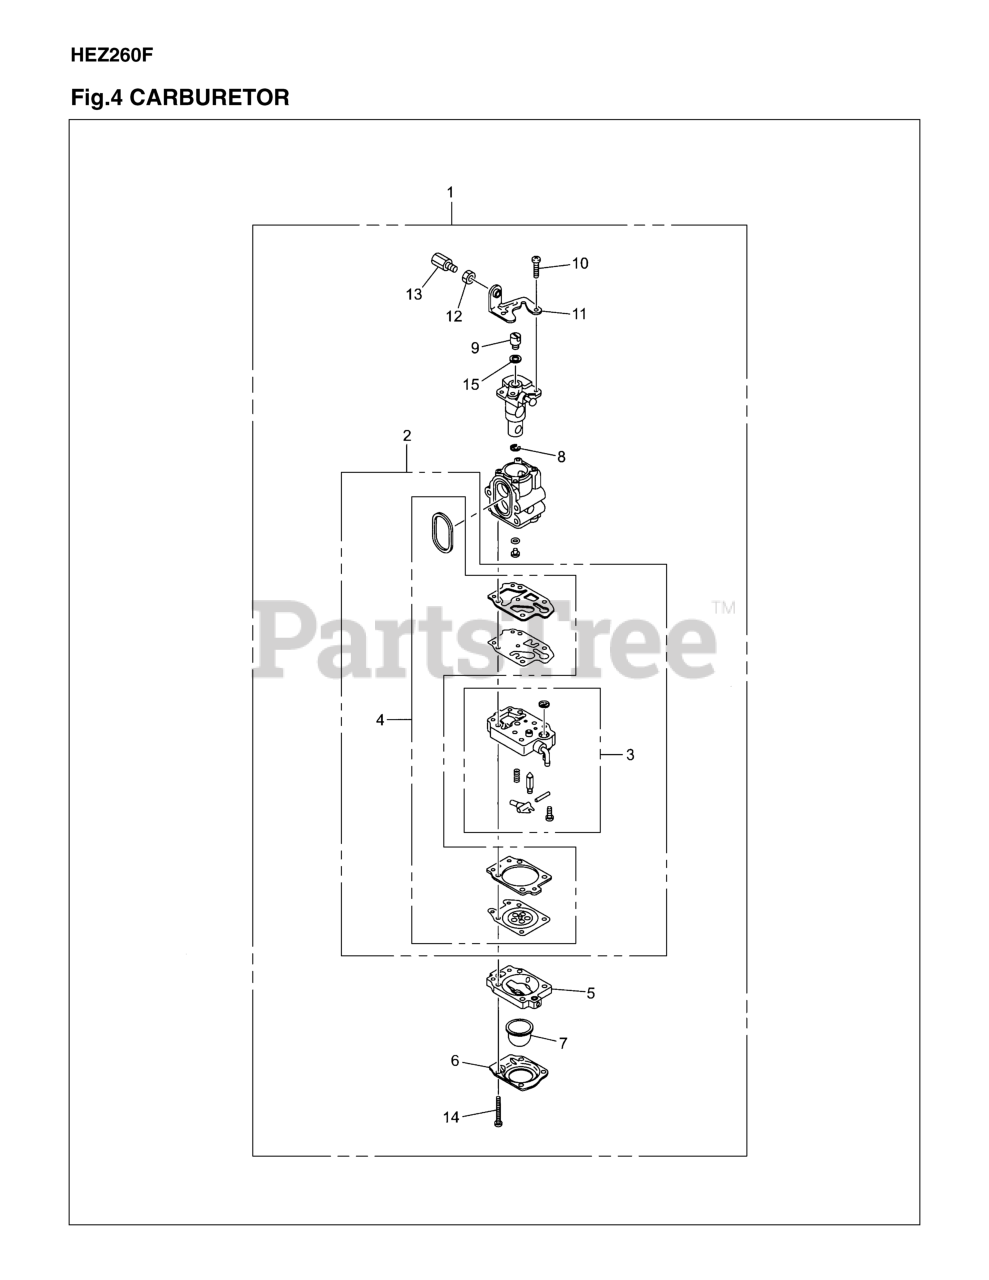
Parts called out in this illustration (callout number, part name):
2	REBUILD KIT
3	CARBURETOR BODY
4	GASKET KIT
6	1OVER
8	RING
9	SWIVEL
10	SCREW
11	BRACKET
12	NUT
13	ADJUSTER
15	WASHER
